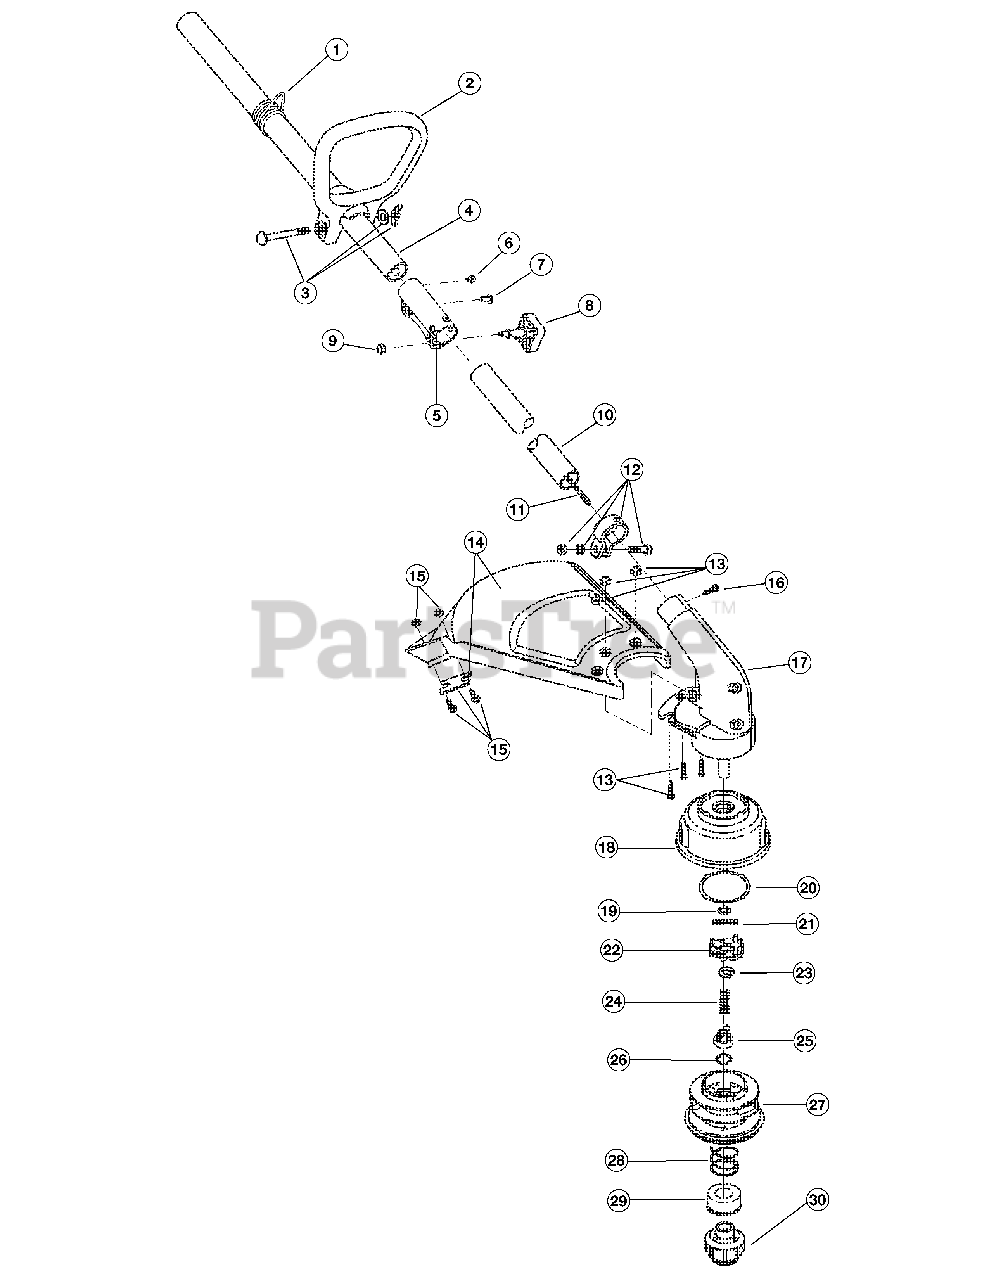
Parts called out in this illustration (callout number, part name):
1	Shoulder Harness Clamp
2	D-Handle
3	D-Handle Hardware Assembly
4	Upper Drive Shaft Housing Assembly
5	Split Boom Coupler (includes 6-9)
8	Adjustment Knob
9	Knob Retaining Nut
10	Lower Drive Shaft Housing Assembly
11	Flexible Drive Shaft
12	Lower Clamp Assembly
13	Guard Mounting Hardware
14	Guard Assembly
15	Blade Assembly
16	Anti-Rotation Screw
17	Gearbox (includes 16)
18	Outer Spool Assembly (includes 19)
19	Retainer
20	Thrust Washer
21	Small Spring
22	Slider
25	Plunger
27	Inner Reel
28	Large Spring
29	Foam Seal
30	Bump Knob Assembly (includes 28 & 29)
